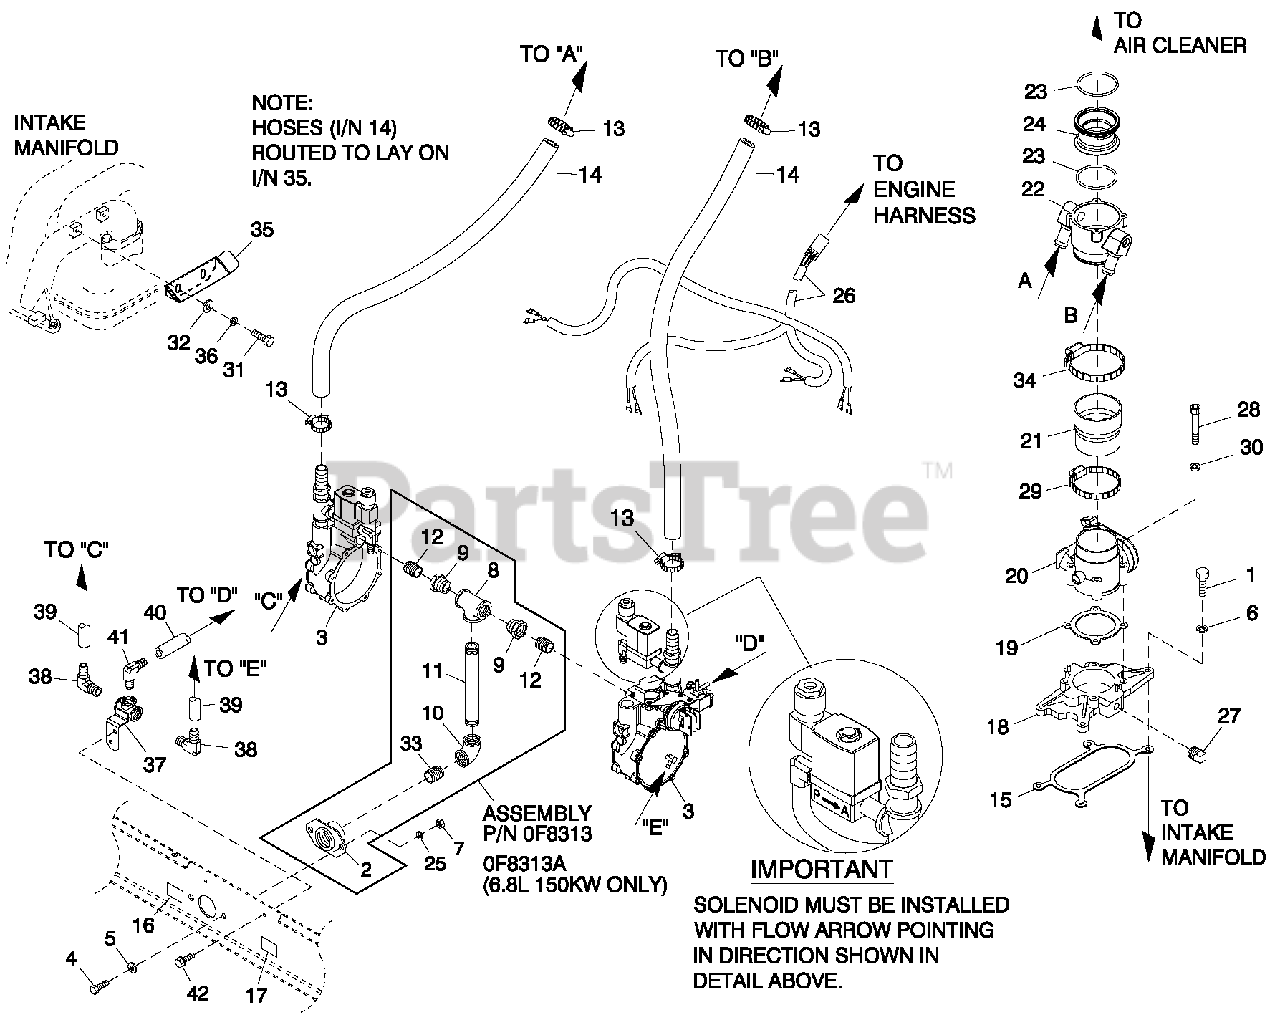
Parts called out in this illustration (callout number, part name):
1	SCREW HHC 5/16-18 X 1-1/4 G5
2	SUPPORT NAT GAS SOLENOID
3	REG 6.8L 100 KW LP CPL EMISS
4	SCREW HHC M12-1.75 X 20 G8.8
5	WASHER FLAT 1/2 ZINC
6	WASHER LOCK M8-5/16
7	NUT HEX M12-1.75 G8 YEL CHR
8	PIPE TEE 1-1/4 NPT
9	BSHG RDCRHEX1-1/4-3/4
10	ELBOW 90D1-1/4 NPT
11	NIPPLE PIPE 1-1/4 NPT X 3 (100KW & 130 KW)
12	NIPPLE CLOSE 3/4X1.375
13	CLAMP HOSE #10 .56-1.06
14	HOSE 3/4 ID SAE-30R2 (45" LG)
15	GASKET ADAPTER THROT BODY
16	DECAL INLET PRESSURE
17	DECAL FUEL INLET LPG
18	ASSY,ADAPTER,THROTTLE BODY
19	GASKET GOVERNOR ACTUATOR
20	ACTUATOR BOSCH 60 GOVERNOR
21	REDUCER 3.0" TO 2.75" TURBO
22	MIXER 40/60MM ACTUATOR ASSY
23	O-RING 2-3/4X3/32X2-15/16
24	VENTURI THROTTLE 42MM (6.8L 100 KW)
25	WASHER LOCK 1/2
26	HARNESS, FUEL JUMPER DUAL REG
27	PLUG STD PIPE 1/4 STEEL SQ HD
28	SCREW SHC M6-1.0 X 50 C8.8
29	CLAMP HOSE #44 2.31-3.25
30	WASHER LOCK M6-1/4
31	SCREW HHC M6-1.0X 20 G8.8
32	WASHER FLAT M6
33	NIPPLE CLOSE 1.25 NPT X 1.625
34	CLAMP HOSE #52 2.81-3.75
35	BRACKET, HOSE RISER
36	WASHER LOCK M6-1/4
37	PIPE TEE W/ BRAC KET WELDED
38	BARBED EL 90 3/16X1/8
39	HOSE VACUUM 5/32 (12.0" LG)
40	HOSE VACUUM 5/32 (10.5" LG)
41	BARBED EL W/VENT (.052")
42	SCREW THF M6-1 X 16 N WA Z/JS
